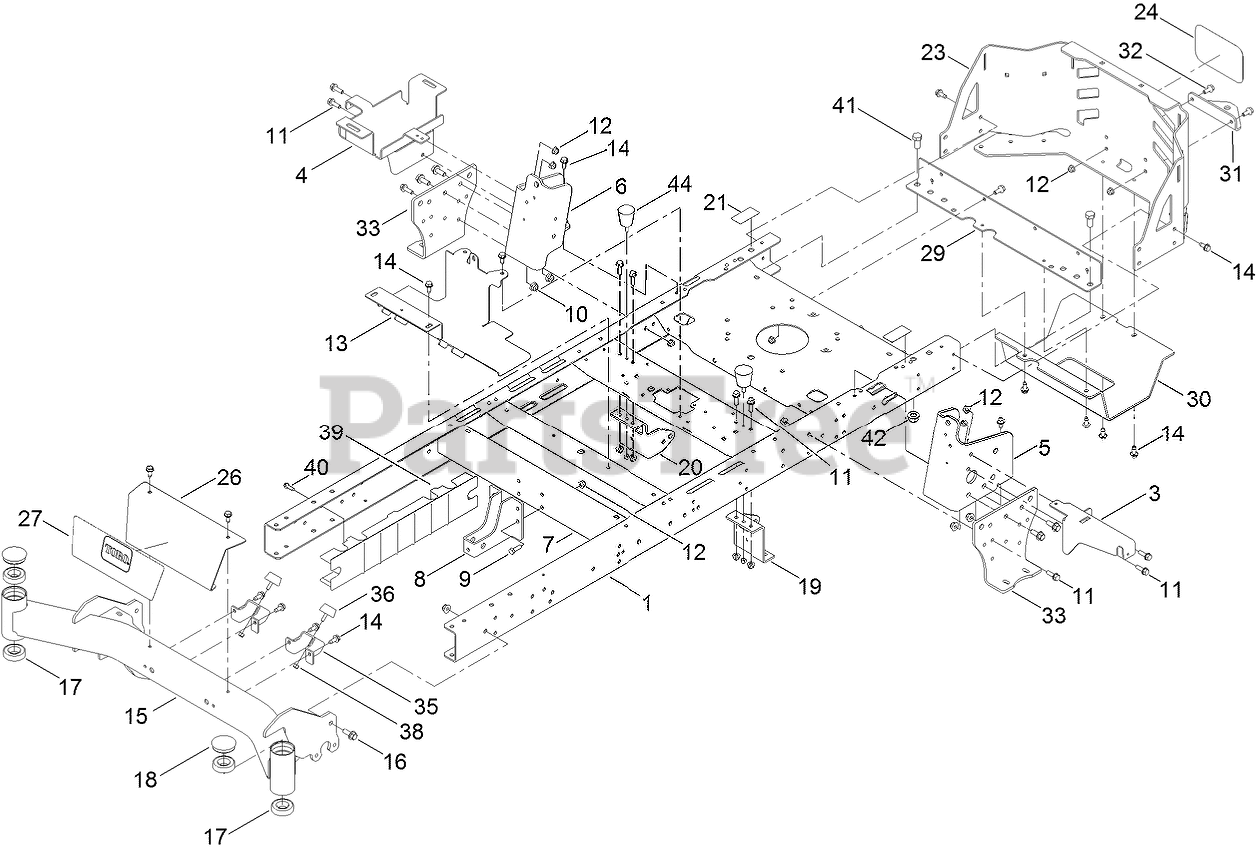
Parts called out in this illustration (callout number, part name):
1	FRAME ASM
3	BRACKET-SUPPORT, POD (LH)
4	TRAY-BATTERY
5	BRACKET-MOUNTING, LH
6	BRACKET-MOUNTING, RH
7	BRACE-CROSS, LOWER
8	BRACKET-MOUNT DAMPER, LOWER
9	SCREW-HH
10	NUT-HF, NI
11	SCREW-HHF
12	NUT-HF
13	BRACKET-MOUNT
14	SCREW-HWHTF
15	AXLE-FRONT
16	SCREW-HHF
17	BEARING-BALL
18	CAP-GREASE
19	MOUNT-HYDRO, FRONT (LEFT)
20	MOUNT-HYDRO, FRONT (RIGHT)
21	DECAL-BYPASS
23	GUARD-ENGINE
24	DECAL
26	PLATE-FRONT
27	DECAL-TIMECUTTER HD
29	CROSSMEMBER-REAR, WIDE
30	GUARD-MUFFLER
31	BRACKET-HITCH
32	SCREW-HHF
33	MOUNT-HYDRO
35	BRACKET-STOP, BUMP
36	BUMPER
38	NUT-HEX
39	GUARD-RAIL
40	SCREW-PLASTITE, HWH
41	SCREW-HH
42	NUT-HF
44	BUMPER-RUBBER
